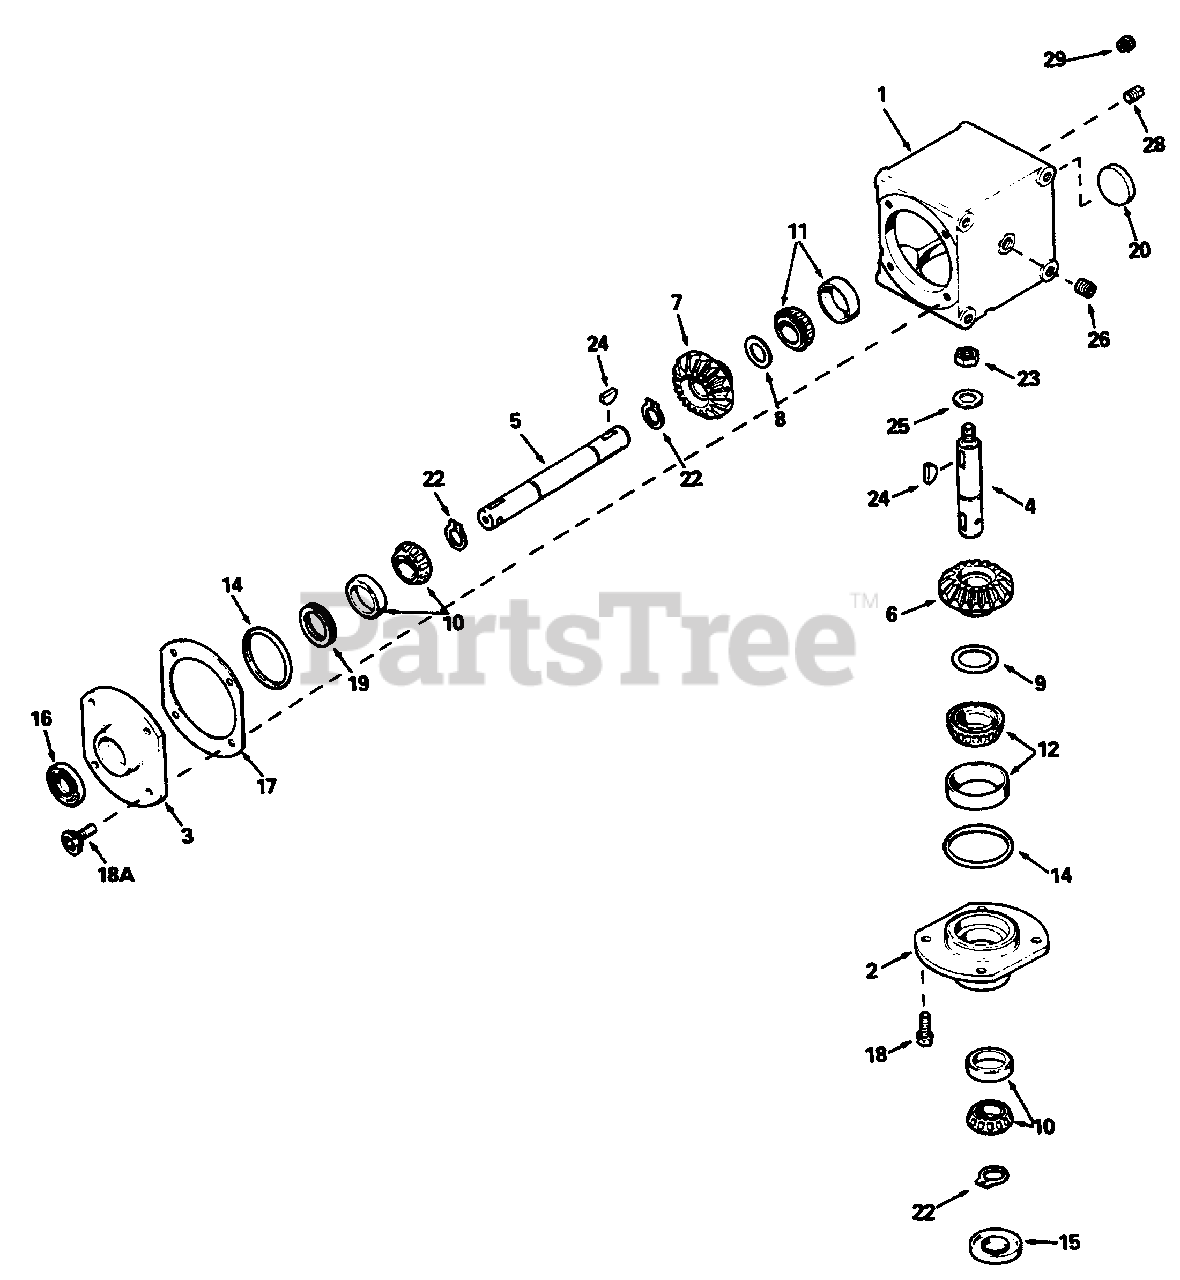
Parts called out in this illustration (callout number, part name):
1	HOUSING, Right Angle Drive
2	CAP, Retainer
3	CAP, Retainer
4	SHAFT, Input
5	SHAFT, Output
6	GEAR, Bevel
7	GEAR, Bevel
8	SHIM, 1-1/2" OD x 1-1/64" ID x .002 Thick
9	SHIM, 2.000" OD x 1.531" ID x .002 thick
10	BEARING & CUP ASSY.
11	BEARING & CUP ASSY.
12	BEARING & CUP ASSY.
15	SEAL, Oil
16	SEAL, Oil
17	SHIM, Cap Retainer
18	SCREW, Hex Hd. Sems, 5/16-18 x 1
18A	SCREW, Flat Socket Hd., 5/16-18 x 7/8
19	RING, Load
22	RING, Retaining
23	JAM NUT, 3/4-16
24	KEY, Woodruff
25	WASHER, Flat
26	PLUG, Pipe, 1/4-18
28	PLUG, Pipe
29	VALVE, Relief
